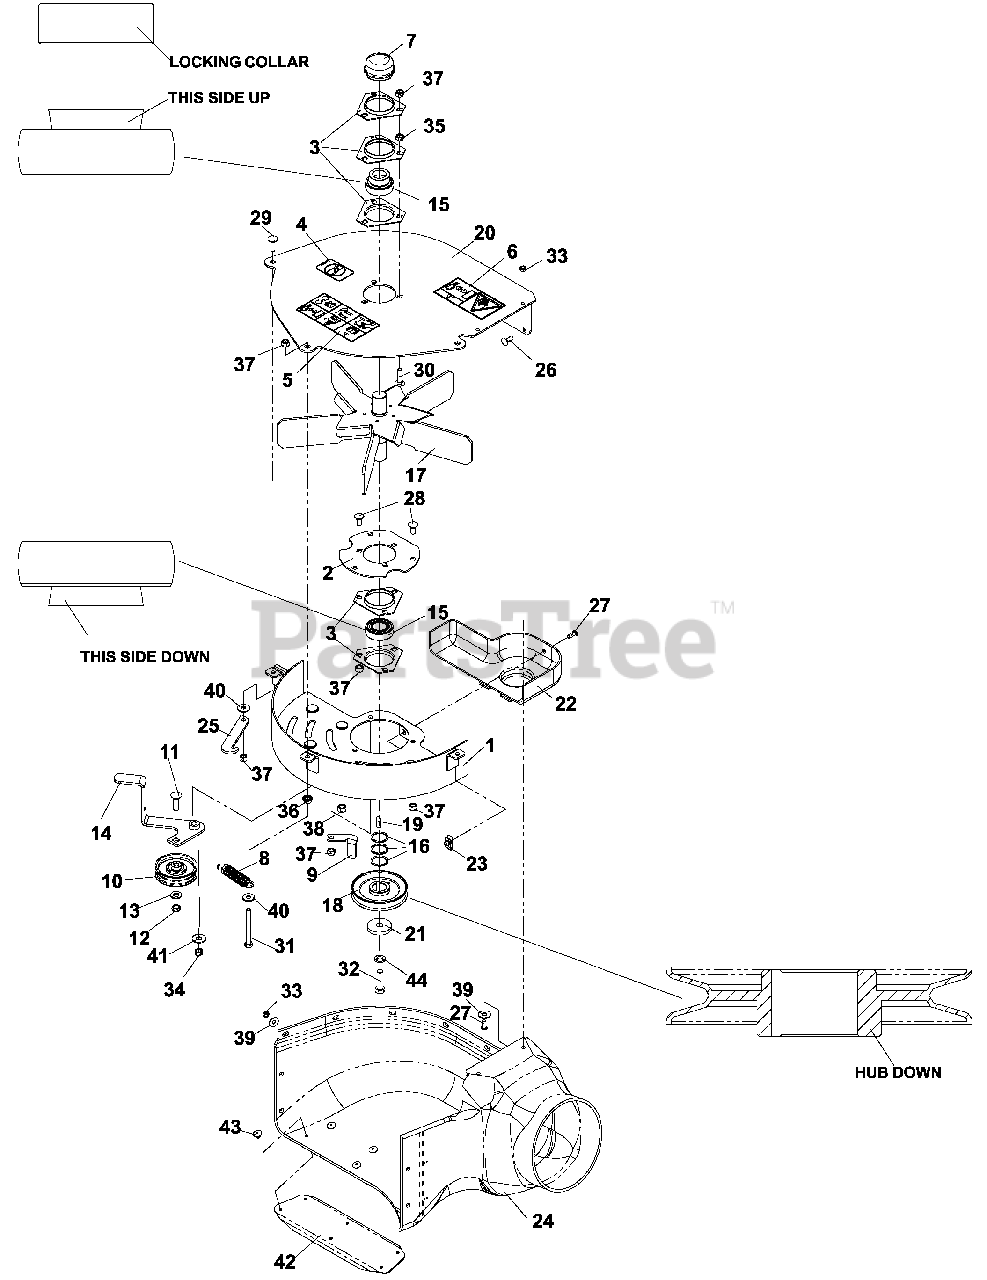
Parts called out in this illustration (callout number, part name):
1	FLOOR WELDMENT
2	BEARING PLATE
4	DECAL, NO STEP
5	DECAL, WARNING
6	DECAL, SERVERING
7	GREASE CAP
9	BELT GUIDE
11	RHSNB, 3/8-16 X 1 1/4, GR5
12	NUT, 3/8-16, JAM NYLOC
13	WASHER, 3/8, SAE
16	BUSHING, MACHINE, 18 GA
17	FAN WELDMENT
18	SHEAVE, 4"
19	KEY, 1/4" SQ. X 3/4"
21	WASHER, HEAVY
22	PULLEY SHIELD
23	RETAINER, 1/4C, "U" TYPE
24	BLOWER HOUSING
25	KEEPER, IDLER
26	RHSNB, 1/4-20 X 3/4, GR2
27	SCREW, 1/4-20 X 5/8, BTN, SKT HD
28	RHSNB, 5/16 X 3/4
29	RHSNB, 5/16-18 X 1, GR5
30	RHSNB, 5/16C X 1 1/4
31	HCS, 5/16-18 X 2 3/4, GR5
32	HCS, 7/16-20 X 1 1/2, GR5
33	NUT, 1/4C, THIN NYLOC
34	NUT, 5/16C, CENTERLOCK
35	NUT, 5/16C
36	NUT, 5/16C
37	NUT, 5/16C, NYLOC
38	NUT, 3/8C, NYLOC
39	WASHER, 1/4
40	WASHER, 5/16
41	WASHER, 3/8
42	BLOWER SUPPORT
44	LOCKWASHER, 7/16
